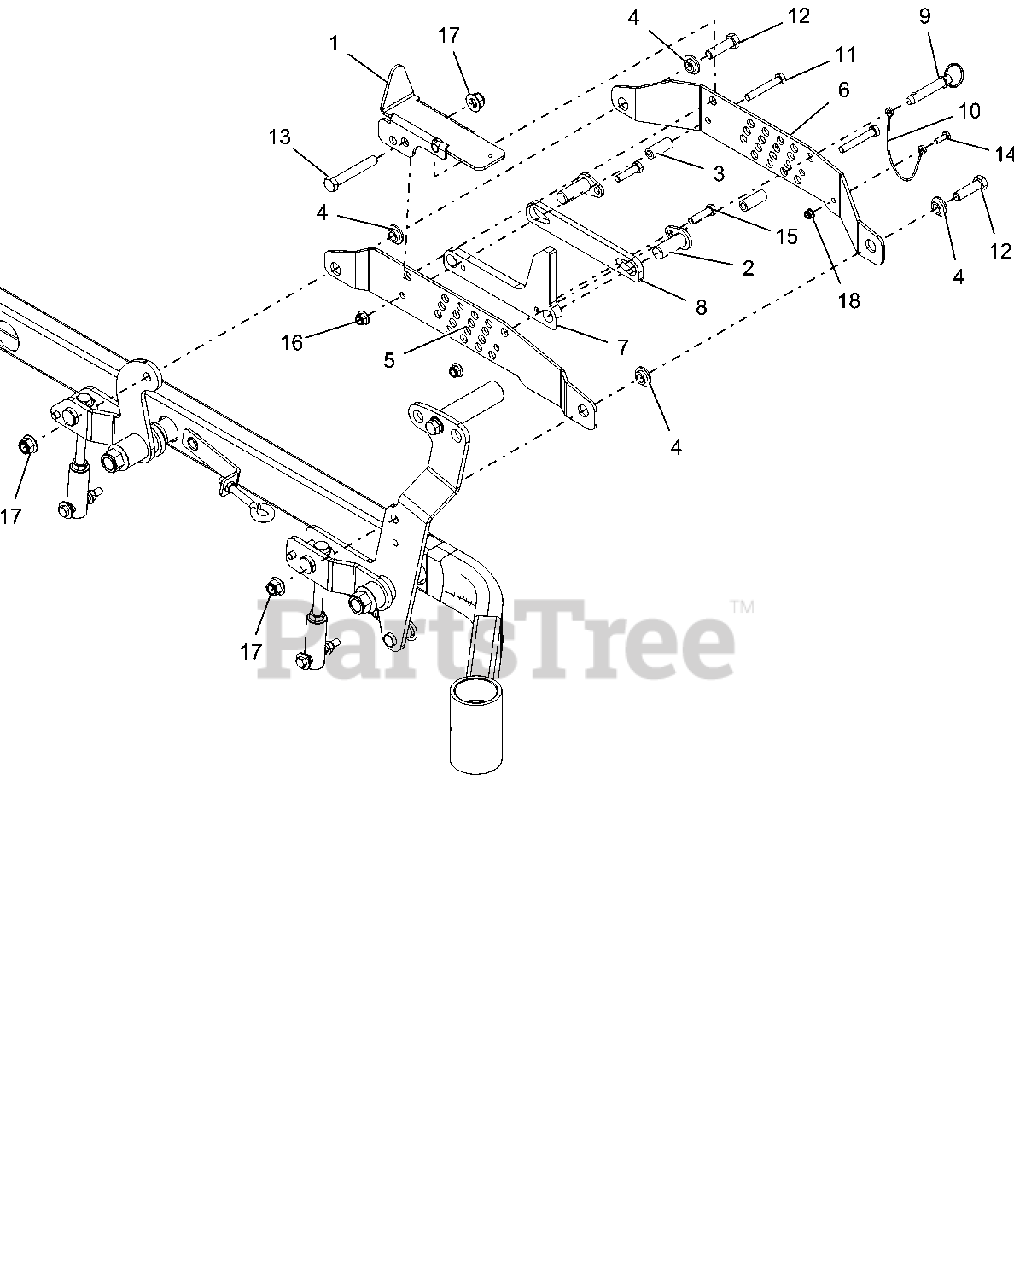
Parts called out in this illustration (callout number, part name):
1	MECHANICAL LOCK-UP WMT - BLACK
2	WLDMT, PIN HOC MOUNTING
3	SPACER, .375 X .625 X 1.54
4	BSHG-FLG .515X.750X.395X1.120
5	RH OTBRRD LIFT/CUT HT BRKT-BLK
6	RH INBRD LIFT/CUT HT BRKT- BLK
7	HOC STOP BRKT - BLK
8	HOC STOP SPACER - BLK
9	PIN, .50 X 2.00 USABLE LG BALL
10	CABLE, 12.0 LANYARD, NYLON
11	@BLT-HEX .38-16X2.50 GR5 YWZC
12	@BLT-HEX .50-13X1.75 GR5 YWZC
13	@BLT-HEX .50-13X3.25 GR5 YWZC
14	@BLT-HEX .25-20X.75 GR5 YWZC
15	BLT,HEX .38-16X1.50 GR5 EP30
16	@NUT-LK-NYL-FLG .38-16 YWZC
17	@NUT-LK-NYL-FLG .50-13 YWZC
18	@NUT-LK-NYL-FLG .25-20 YWZC
